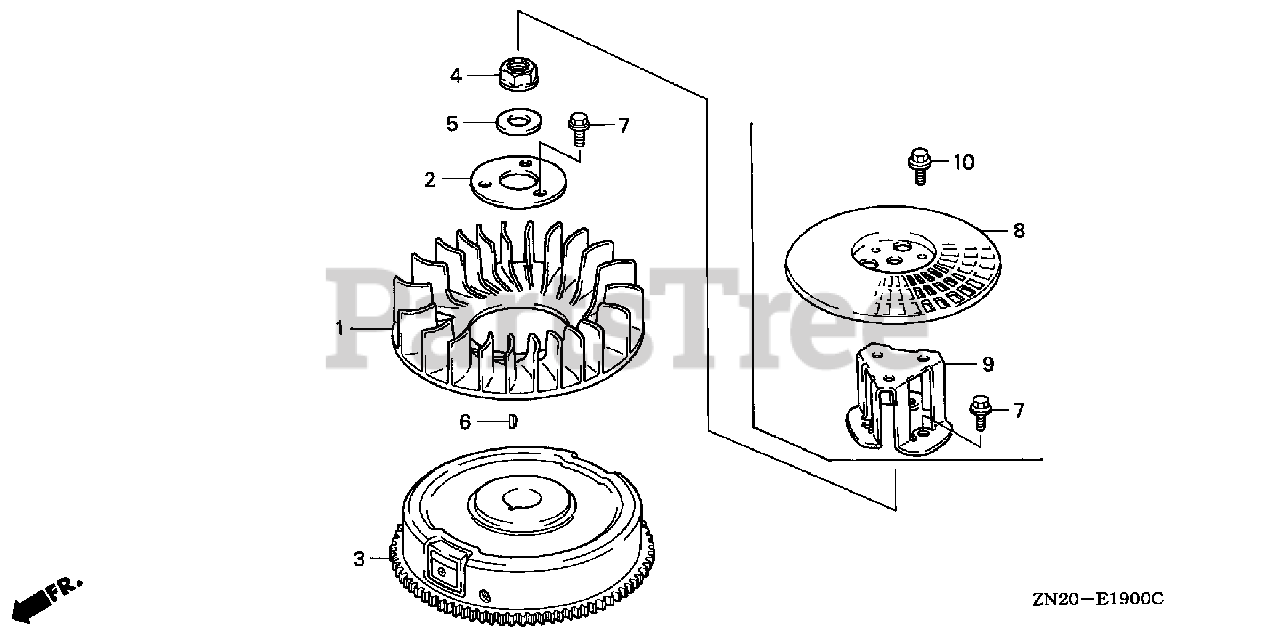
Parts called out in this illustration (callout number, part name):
1	FAN, COOLING
3	FLYWHEEL
4	NUT, FLANGE (20MM)
5	WASHER (20MM)
6	KEY, SPECIAL WOODRUFF (25X18)
7	BOLT, FLANGE (8X16)
8	GRID, SCREEN
9	HOLDER, SCREEN GRID
10	BOLT, FLANGE (6X12)
